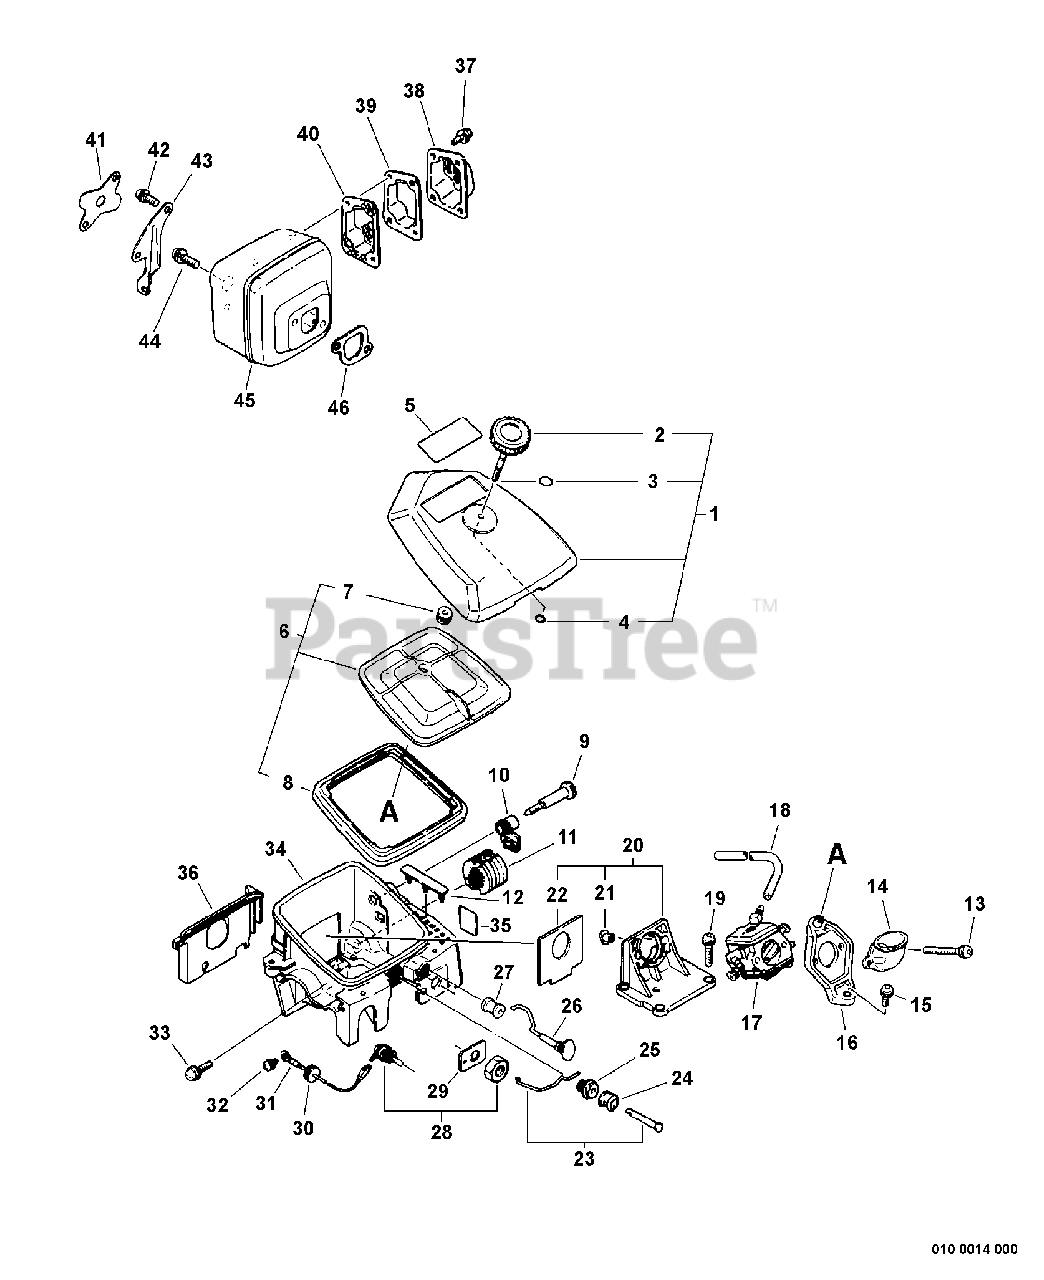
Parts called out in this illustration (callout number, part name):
1	AIR FILTER COVER ASSY
2	THUMBSCREW
3	O-RING - 10
4	O-RING - 3
5	LABEL - MODEL CS-8000
6	FILTER, AIR
9	SCREW, IDLE ADJUST
12	PLUG
13	SCREW - 5X55
14	PLATE, PREVENT
15	SCREW - 5X20
16	BRACKET, AIR CLEANER
17	CARBURETOR
18	PIPE - IMPULSE
19	SCREW - 5X25
20	INSULATOR, INTAKE
21	NUT
22	SEAL, DUST
23	ROD, THROTTLE
25	GUIDE, THROTTLE ROD
26	ROD, CHOKE
28	IGNITION SWITCH ASSY
29	LABEL - STOP
31	LEAD - GROUND
32	SCREW - 4X8
33	SCREW - 4X8
34	CASE, CARBURETOR
36	PLATE, GUIDE
37	SCREW - 4X10
38	GUIDE, EXHAUST - OUTER
39	GUIDE, EXHAUST - INNER
40	SCREEN, SPARK ARRESTOR
41	COVER, MUFFLER
42	SCREW - 5X14
43	BRACKET, MUFFLER
44	SCREW - 6X20
46	GASKET, EXHAUST
